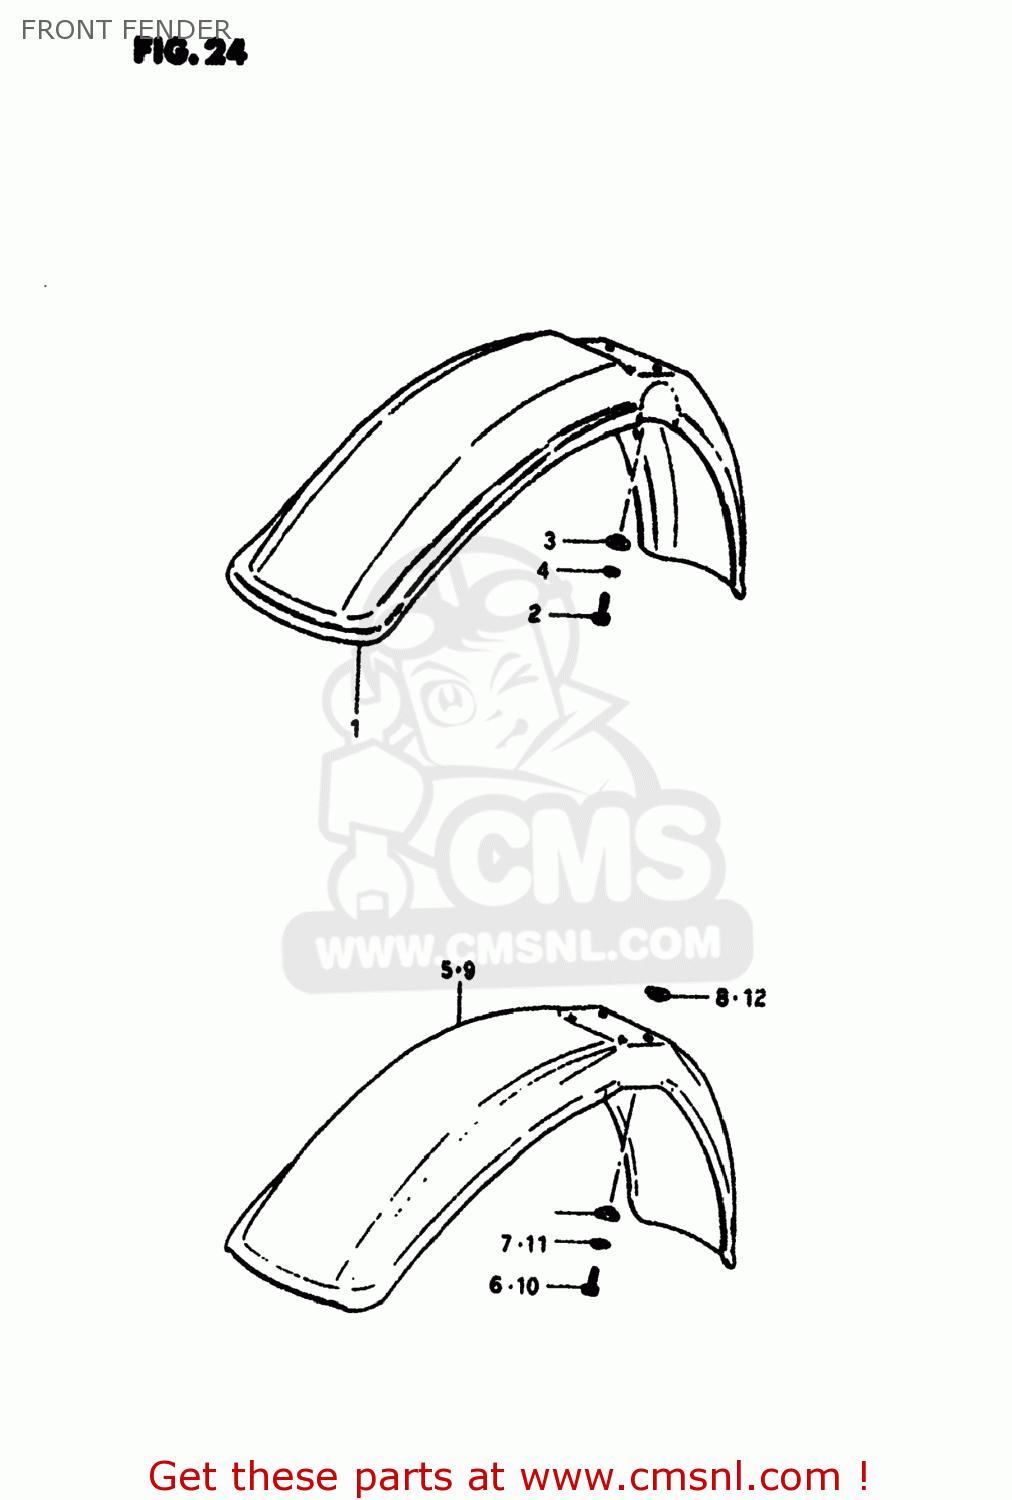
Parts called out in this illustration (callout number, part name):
1	FENDER,FRONT
2	BOLT, UPPER
3	SPACER
4	LOCK WASHER
5	FENDER,FRONT
6	BOLT, UPPER
7	LOCK WASHER
8	WASHER
9	FENDER,FRONT
10	BOLT, UPPER
11	LOCK WASHER
12	WASHER
